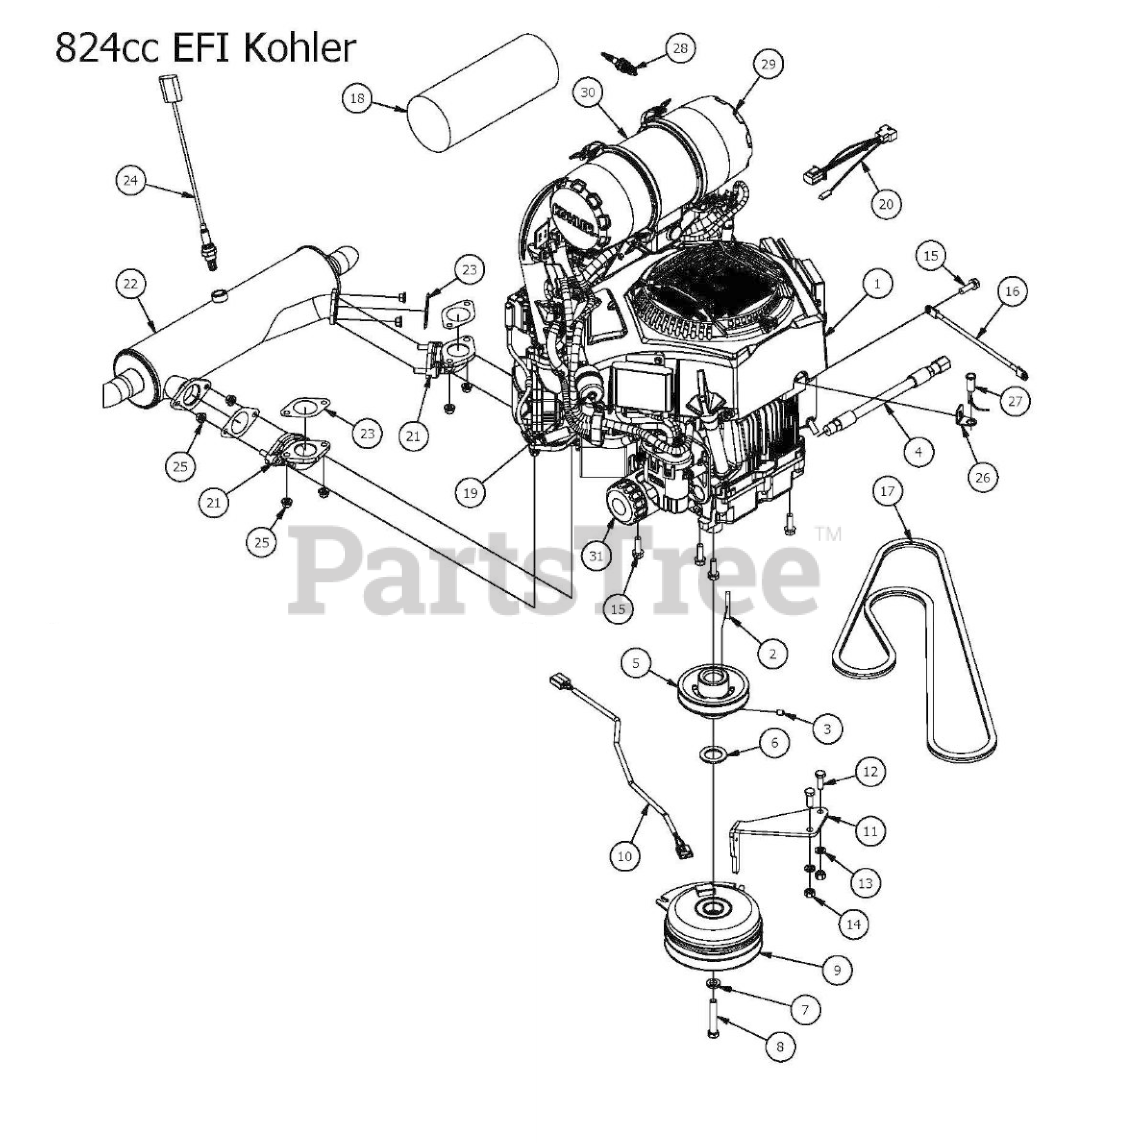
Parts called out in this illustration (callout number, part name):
1	824cc EFI Kohler
2	1/4 x 2 Square key Stock
3	3/8" Set Screw
4	Oil drain Hose
5	4 3/4 Motor Pulley
6	1 1/8" Flat Spacer
7	7/16" Lock Washer
8	7/16" x 2 1/2" Hex Bolt
9	Clutch Assembly
10	Clutch Pigtail
11	PTO Engager Holder
12	3/8" x 1" Hex Bolt
13	3/8" Lock Washer
14	3/8" Hex Nut
15	3/8 x 1 1/8 bolt
16	Ground Cable
18	Canister Air Filter-Outer
19	Universal Inline Fuel Filter
20	Harness Adaptor - 824cc EFI Kohler
21	Cast 90 Elbow
22	824cc Kohler Exhaust
23	Exhaust Gasket for 824EFI Kohler
24	02 Sensor for 824EFI Kohler
25	M8.125 Mechanical locking Flange Nut
26	EFI Light Bracket
28	Spark Plug Kohler EFI
29	Kohler End Cap
30	Kohler Air Canister Complete
31	Oil Filter
